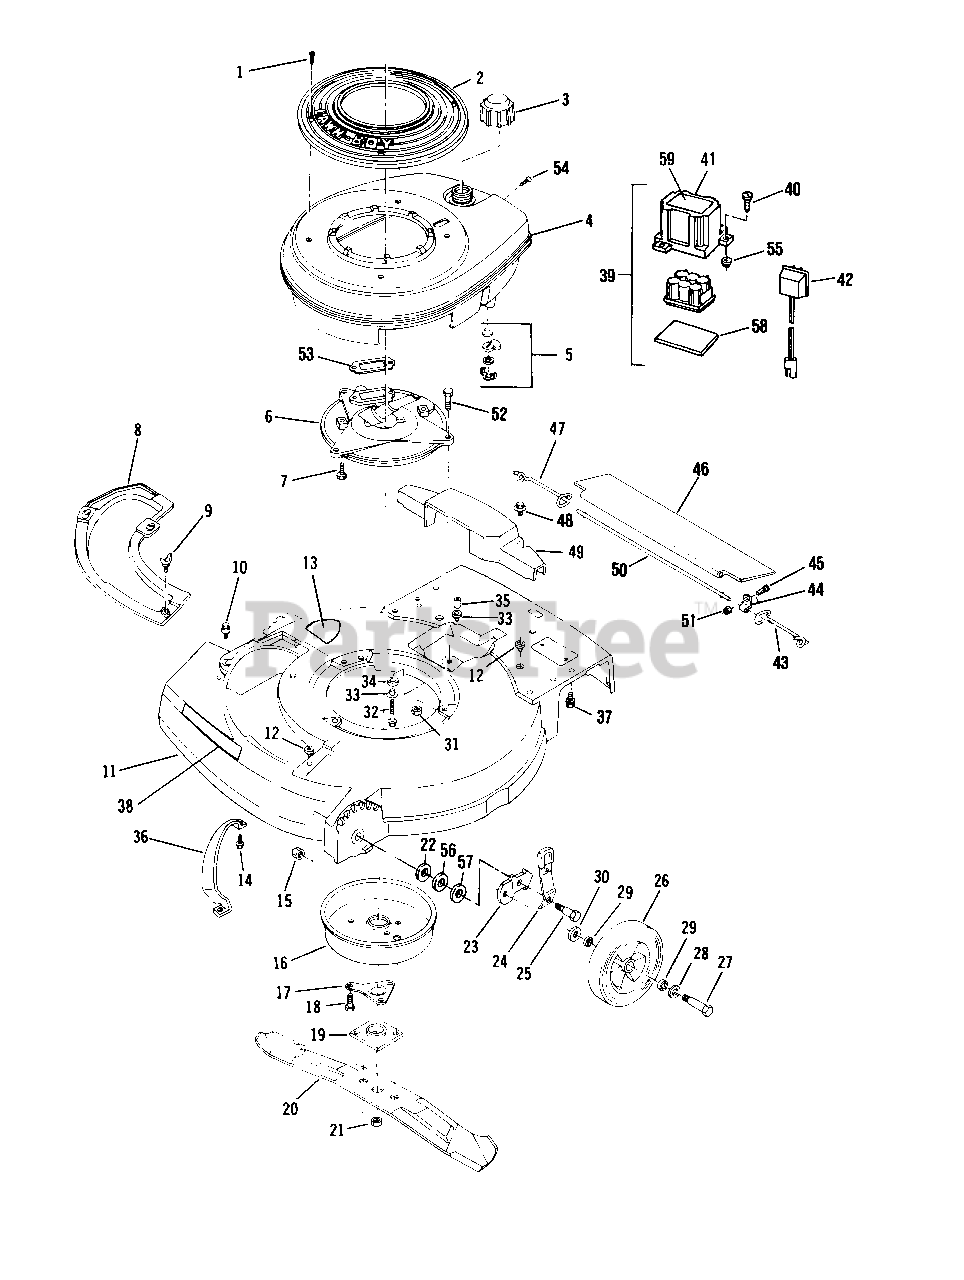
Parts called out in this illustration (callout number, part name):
1	Screw
2	Cover-Shroud
3	Fuel Cap
4	Shroud-Engine
5	Fuel Shut-Off Assembly
6	Plate-Muffler
7	Screw-Muffler Plate to Block
8	Cover Plate
9	Wing Screw
10	Screw-Plate and Chute Mounting
11	Housing
12	Grommet
13	Decal-Blade Contact Warning
14	Screw
15	Nut
16	Muffler Cover Assembly
17	Support-Crankshaft
18	Screw-Muffler to Muffler Plate
19	Collar and Plate Assembly
20	Blade-21"
21	Nut-Blade
22	Washer
23	Bracket-Wheel Height Adjuster
24	Knob and Spring Assembly
25	Bolt-Shoulder
26	Wheel-Front
27	Bolt-Wheel-Front
28	Washer
29	Washer-Felt
30	Washer
31	Nut-Muffler Plate to Housing
32	Screw
33	Spacer
34	Grommet
35	Spacer
36	Toe Bar
37	Screw-Handle Bracket
38	Decal-Headliner
39	Battery Pack Assembly
40	Screw-Battery Cover
41	Cover-Battery
42	Battery Charger Assembly
43	Spring-L.H.
44	Clamp
45	Screw
46	Shield-Trailing
47	Spring-R.H.
48	Screw-Axle Cover Mounting
49	Cover-Drive Axle
50	Rod-Trailing Shield
51	Nut
52	Screw-Muffler Plate to Housing
53	Gasket-Exhaust
54	Screw-Shroud to C.D. Bracket
55	Grommet-Battery Mounting
56	Washer-Shim
57	Washer-Shim
58	Pad Battery
59	Decal-Battery
